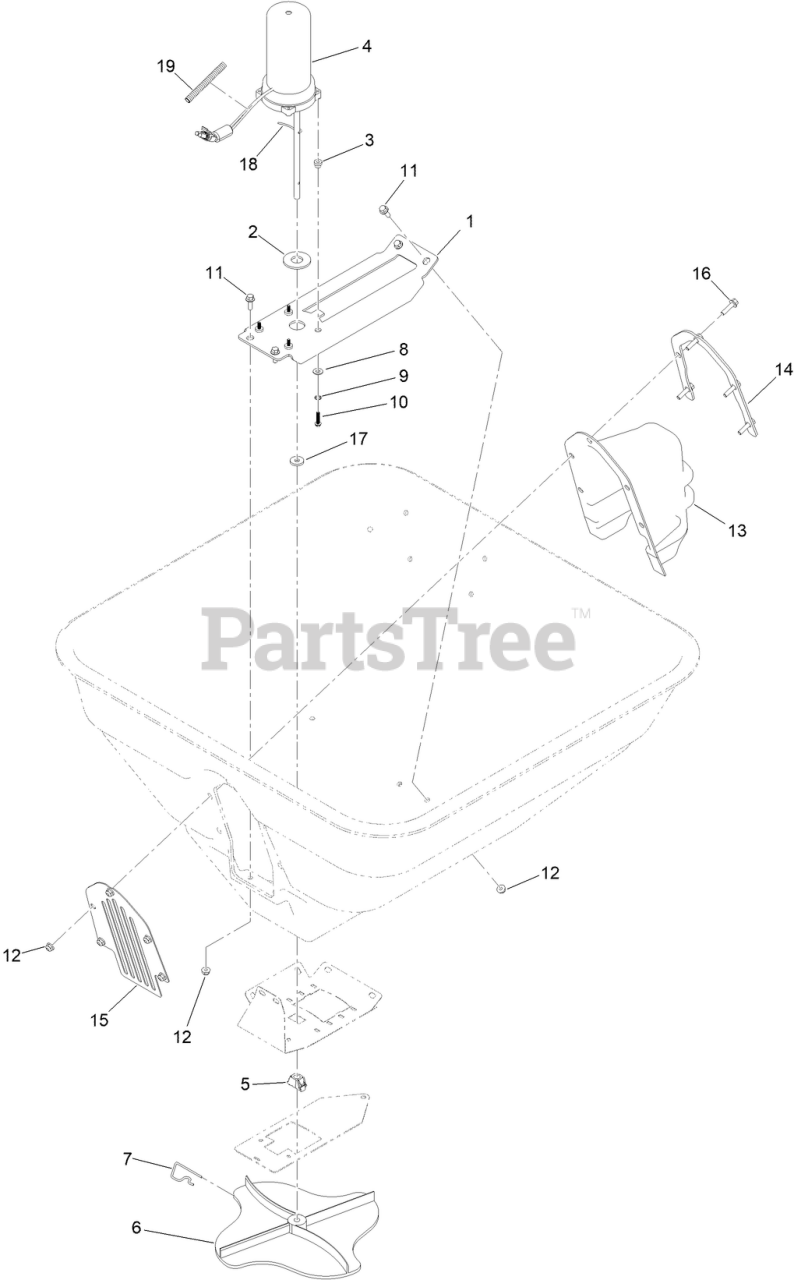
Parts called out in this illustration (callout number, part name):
1	BRACKET-MOUNT, MOTOR
3	SPACER-FLANGED
4	MOTOR-SPREADER
5	HOPPER BOTTOM BEARING
6	Spinner-Spreader
7	Clip-Spinner
8	WASHER-FLAT
9	WASHER-LOCK, INT
10	SCREW-SHWH
11	Screw-HHF
12	Nut-Hex Flange
13	COVER-MOTOR
14	FLANGE-COVER, MOTOR
15	COVER-FRONT, MOTOR
16	SCREW-HHF
17	WASHER-FELT
18	WIRE-AGITATOR
19	LOOM-SPLIT
